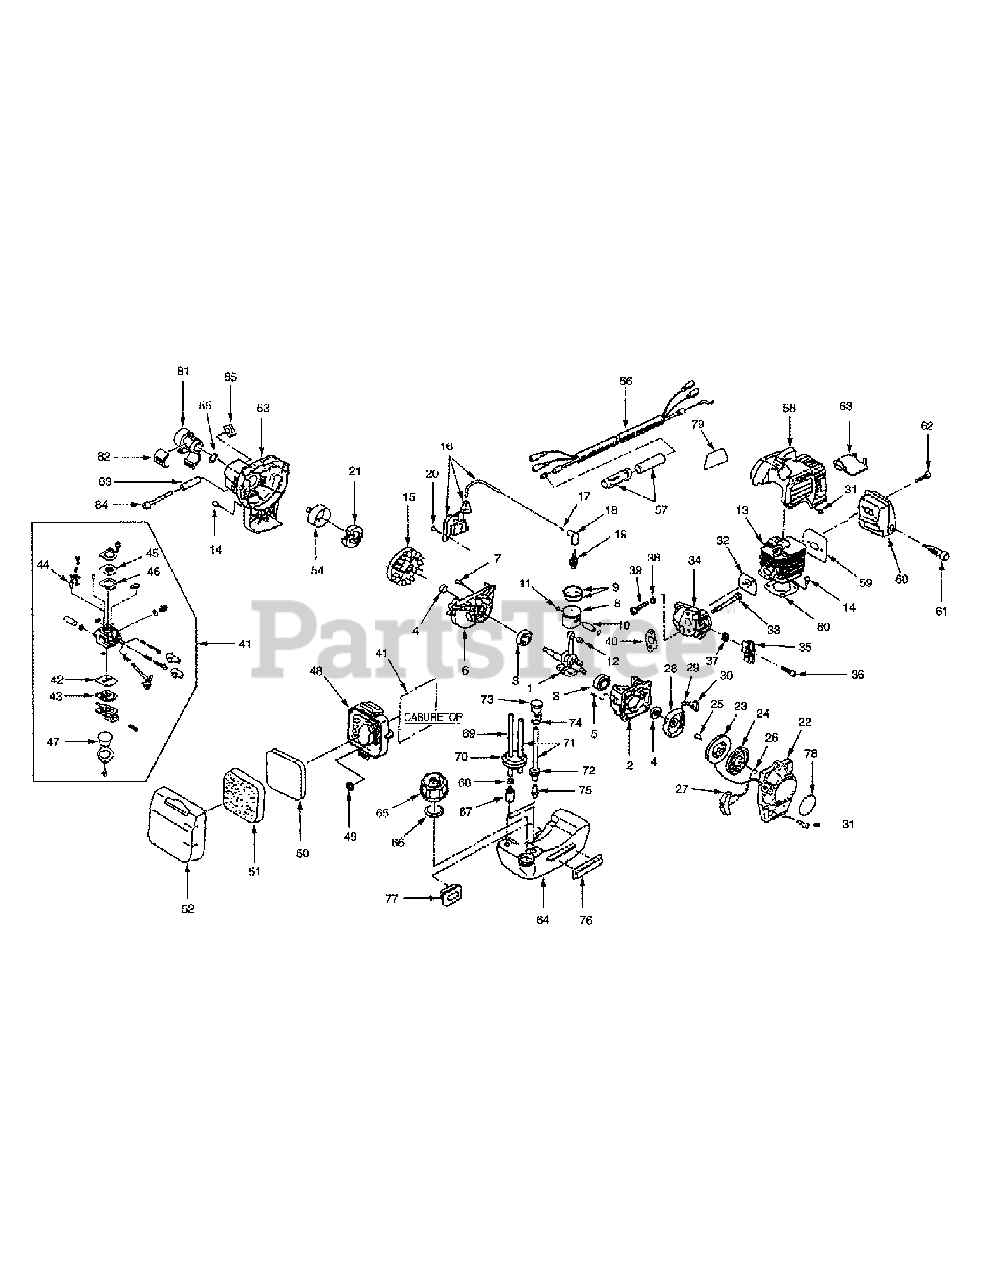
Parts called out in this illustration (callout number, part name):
1	Crankshaft
2	Crankcase Assembly
3	Bearing Ball, 6201
4	Seal, Oil
5	Pin, Dowel
6	Crankcase Assembly
7	Bolt, M5x25
8	Piston Assembly
9	Ring, Piston
10	Pin, Piston
11	Clip, Piston Pin
12	Bearing, Needle
13	Cylinder
14	Bolt, M5x16
15	Flywheel, Magneto
16	Coil Assembly, Ignition
18	Cap ,Plug
19	Spark, Plug
20	Bolt, M4x20
21	Clutch Assembly
22	Recoil Assembly
24	Spring, Spiral
26	Rope, Starter
27	Knob, Starter
28	Pulley Assembly, Starter
29	Spring, Return
31	Bolt, M5x20
32	Gasket, Insulator
33	Bolt, M5x56
34	Insulator
35	Adjuster
36	Bolt, M5x12
38	Washer
39	Bolt, M5x25
40	Gasket
41	Carburetor Assembly
42	Diaphragm, Pump
43	Gasket, Pump
44	Valve, Float
45	Diaphragm, Metering
48	Case, Air Silencer
50	Element "B", Air Filter
51	Element "A", Air Filter
52	Cap, Case
53	Housing, Blower
54	Drum, Clutch
55	Snap Ring, S-12
56	Wire Complete, Throttle
57	Wire Holder
58	Cowling, Cylinder
59	Gasket, Muffler
61	Arrester
62	Bolt, M5x48
63	Plate, Baffle
64	Tank, Fuel
65	Cap Assembly, Fuel Tank
67	Filter, Fuel
69	Hose
71	Hose
73	Valve, Revrsing
75	Connector
76	Rubber
78	Name Plate
79	Trade Mark
80	Gasket, Cylinder
84	Bolt, M5x30
